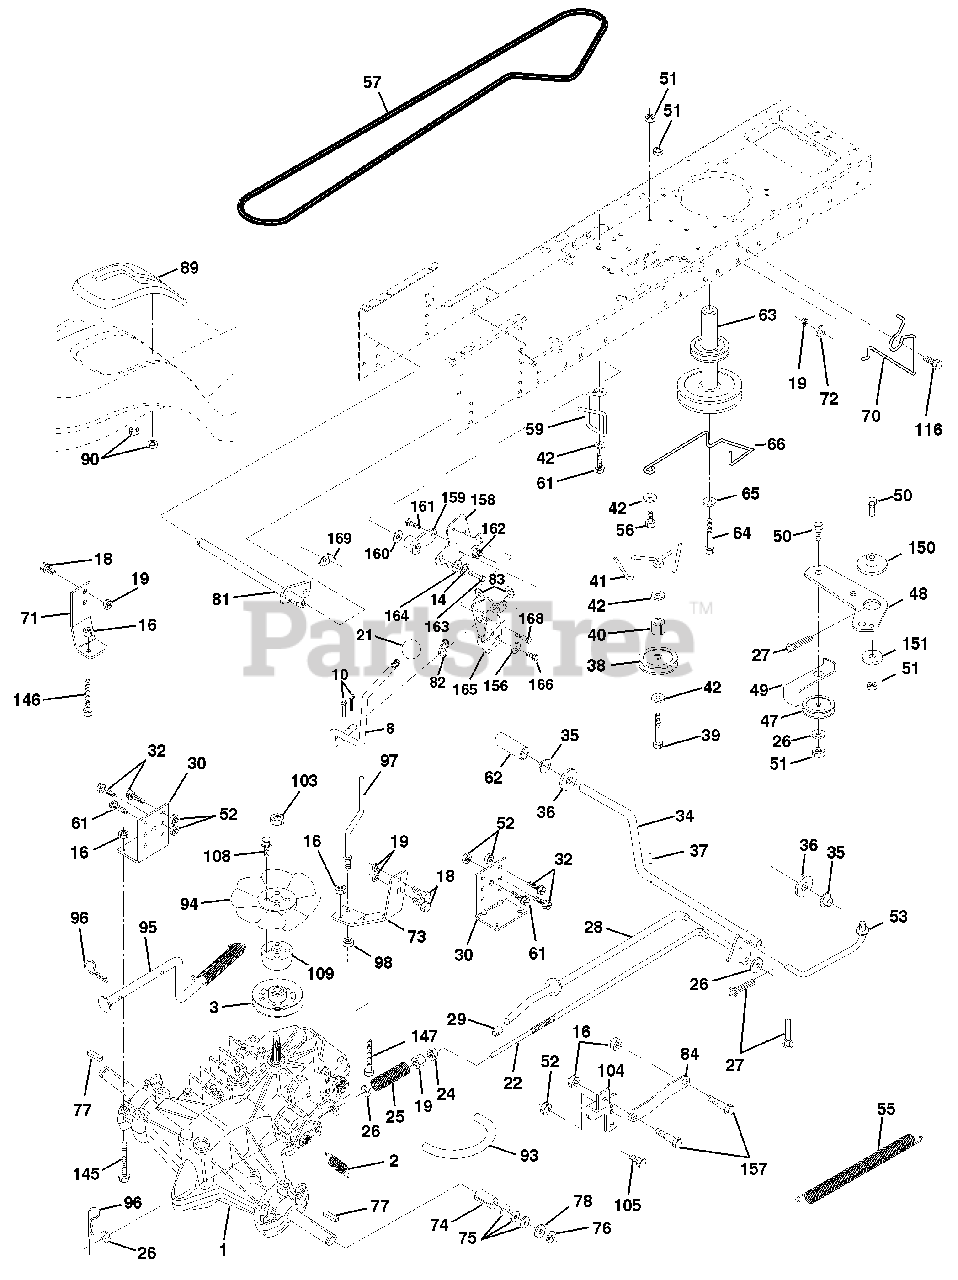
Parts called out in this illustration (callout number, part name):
1	Transaxle Assy Hydro Gear 310-0500
2	Spring, Return, Brake
3	Pulley, Transaxle
8	Rod Shift Fender Adjust
10	Pin Cotter 1/8 x 1 CAD
14	Washer Lock Hvy Helical
16	Nut Lock Hex W/Ins 5/16-18 Unc P
18	Bolt Fin Hex 3/8-16 Unc x 1 Gr. 5
19	Nut Lock Hex W/Wsh 3/8-16 Unc
21	Knob 1/2-13
22	Rod, Brake Hydro
24	Nut
25	Spring, Brake Rod
26	Washer
27	Pin Cotter 1/8 x 3/4 CAD.
28	Rod, Parking Brake
29	Cap, Parking Brake
30	Bracket, Transaxle
32	Bolt Hex Hd 5/16-18 Unc x 3/4
34	Shaft, Foot Pedal
35	Bearing, Nylon
37	Pin, Roll
38	Pulley, Idler, Flat
40	Spacer, Split
41	Keeper, Belt Retainer
42	Washer 13/32 x 13/16 x 12 Gauge
47	Pulley, Idler, V-Groove
48	Bellcrank Clutch Grnd Drv STL
49	Retainer, Belt
50	Bolt
51	Nut Crownlock 3/8-16
52	Nut Crownlock 5/16-18
53	Link, Clutch
55	Spring, Return, Clutch
56	Bolt Fin Hex 3/8-16 Unc x 1-1/4
57	V-Belt, Ground Drive
59	Keeper, Center Span
61	Screw Thdrol. 3/8-16 x 3/4 Ty. TT
62	Cover, Pedal
63	Pulley, Engine Mech 38" Deg Hydro
64	Bolt, Hex
65	Washer
66	Keeper, Belt Engine F-Proof
70	Keeper Belt Engine
71	Strap Torque Lh Hydro 500 18"
72	Washer 13/32 x 1-1/4 x 12 Gauge
73	Strap Torque Rh Hydro 500 18"
74	Spacer, Split
75	Washer 25/32 x 1-1/4 x 16 Gauge
77	Key, Square
78	Washer 25/32 x 1-5/8 x 16 Gauge
81	Shaft Asm. Cross Tapered
82	Spring Torsion T/A
83	Washer 17/32 x 3/4 x 16 Ga.
84	Link Transaxle
87	Washer 21/32 x 1-1/4 x 16 Ga.
88	Ring Klip #5304-62
89	Console, Shift Hydro STLT
90	Nut Self-Thd Wsh-Hd 1/4 Zinc
93	Line Fuel Hydro 4"
94	Fan, Hydro 7"
95	Control Asm. Bypass Hydro
96	Retainer Spring 1" Zinc/Cad
97	Keeper Belt Rh Hydro 500
98	Nut Keps Hex 3/8-16 Unc
100	Washer 11/32 x 3/4 x 16 Ga.
103	Nut, Hex Jam Toplock 1/2-20 Unf
104	Arm, Control Pump
105	Screw Cap Hex 5/16 x 18 x 1
106	Bolt Fin Hex 5/16-18 Unc x 1-1/4
108	Screw Hex Wh Hd #10-24 x 1-5/8
109	Adaptor Fan/Hydro Lt Hyd Alum
116	Bolt, RDHD SQ Neck 3/8-16 x 1.25
144	Washer 11/32 x 5/8 x 16 Ga.
145	Bolt Hex Flghd 5/16-18 x Gr. 5
146	Bolt Hex Flg Hd 5/16-18 x 2-1/4
147	Bolt Hex Flg Hd 5/16-18 x 1-1/2
149	Spacer Retainer PM Mower
150	Bushing Bellcrank Grd Drive
151	Washer 13/32 x 2 x 10 Ga.
156	Washer Srrted 5/16 ID x 1.125
157	Bolt Shoulder 5/16-18 Unc - 2A
158	Bracket Shift Mount
159	Hub Tappered Flange Shift Lt
160	Washer 29/32 x 1-1/4 x 16 Ga.
161	Bolt Rdhd Sqnk 1/4-20 x 3/4 Gr. 5
162	Nut Crownlock 1/4-20 Unc
163	Bolt Hex Fin 1/4-20 Unc x 1 Gr5
164	Washer 5/8 x .281 x 10 Ga
165	Bracket Pivot Lever
166	Screw 5/16-18 x 5/8
168	Bolt Shoulder 5/16-18 x .561
169	Plate Fastening
